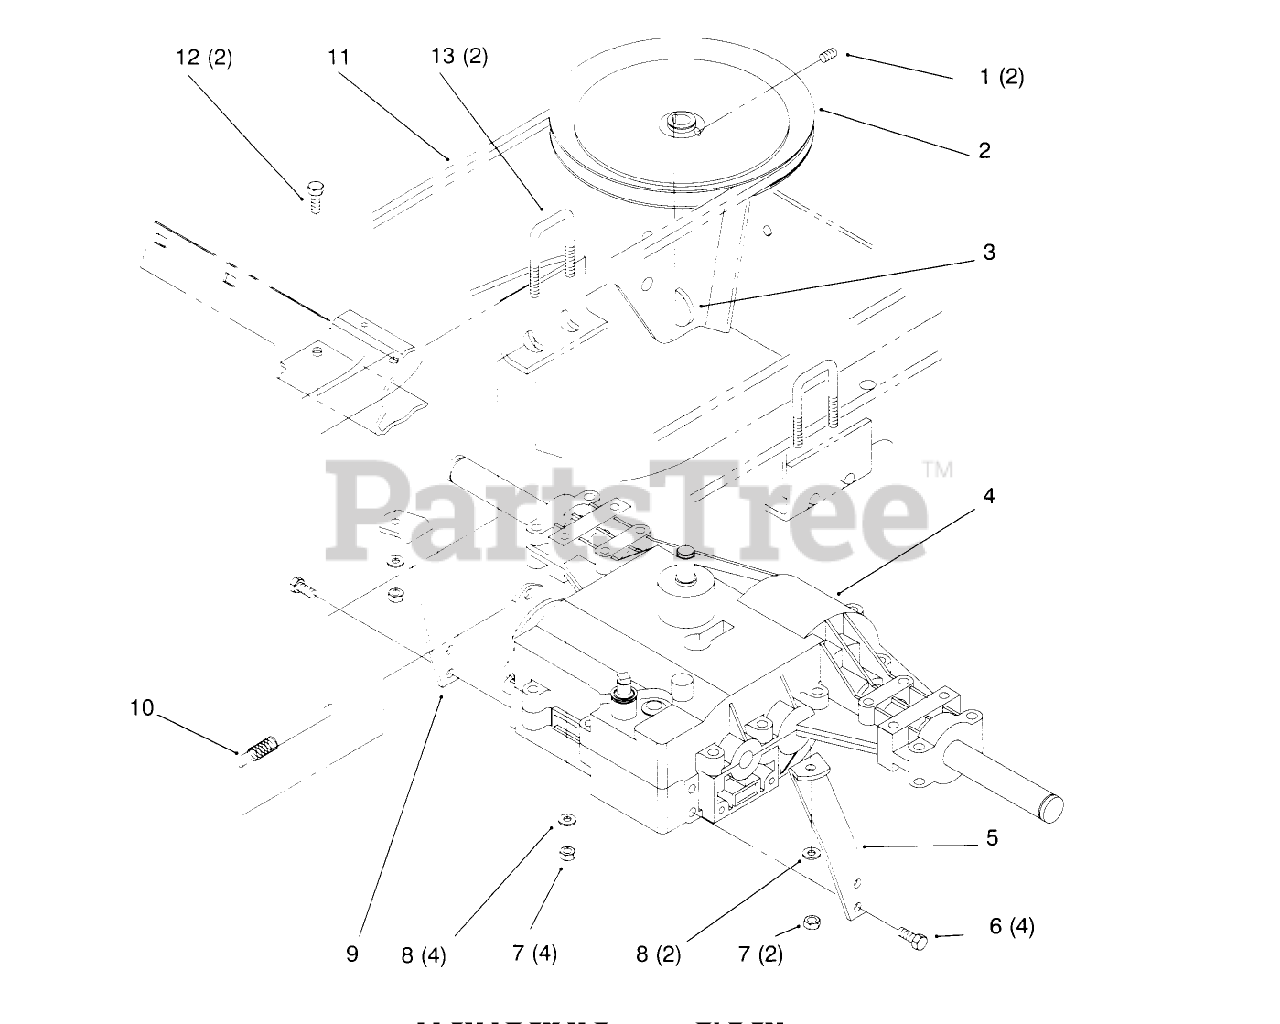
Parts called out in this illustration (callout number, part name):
1	SCREW-SQ HD SET
2	PULLEY-TRANS (GEAR)
3	KEY-HI-PRO
4	TRANSAXLE 820-024
5	STRAP - LH TORQUE
6	SCREW-HWHTF
7	NUT-LOCK, NI
8	WASHER-PLAIN
10	SPRING-EXTENSION
12	SCREW-HH
13	U-BOLT
